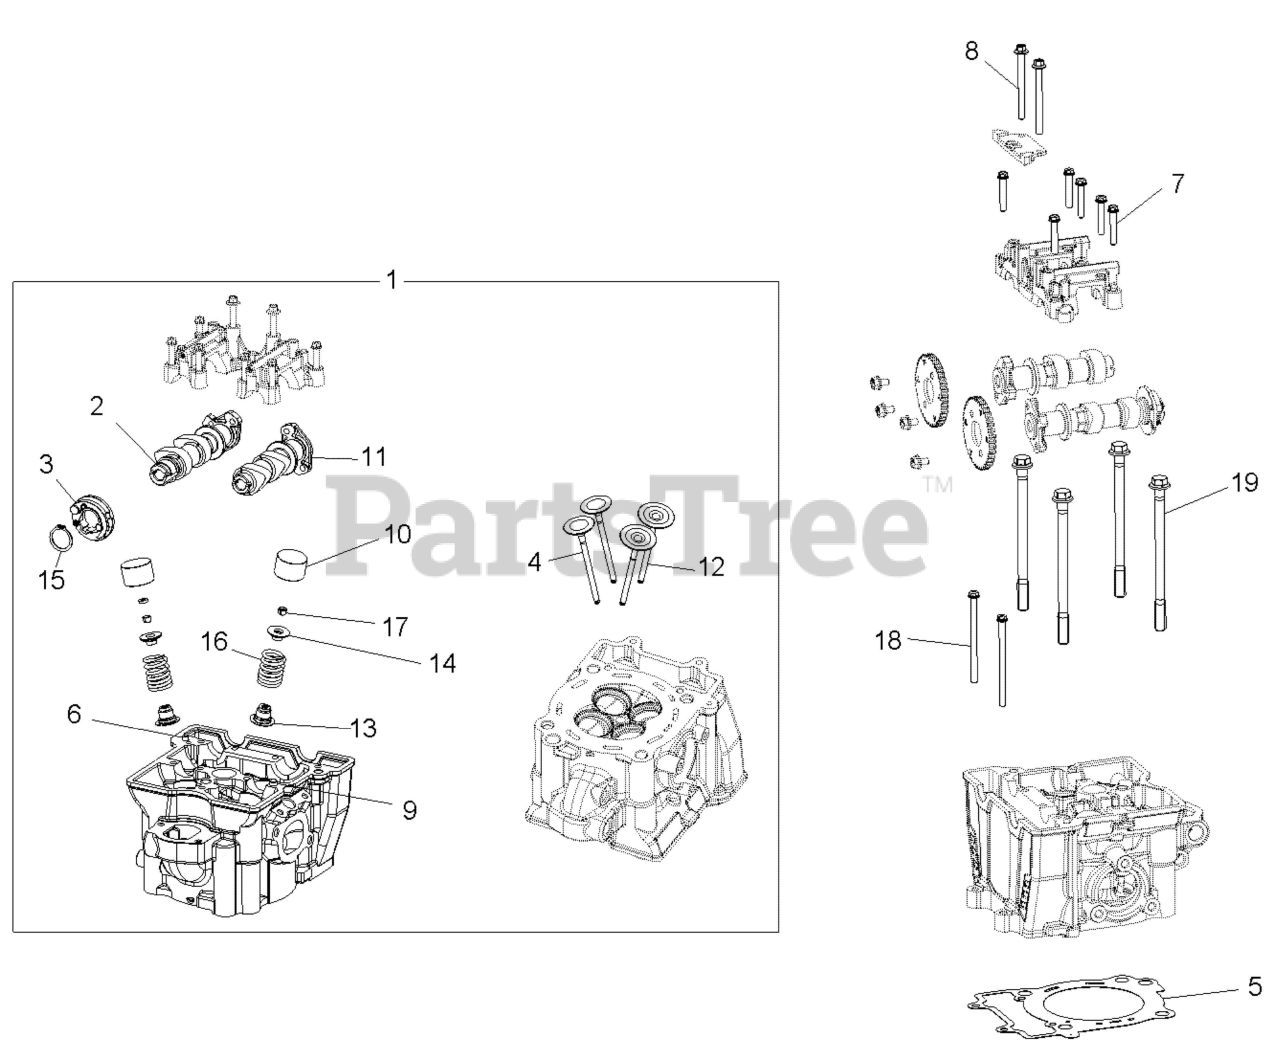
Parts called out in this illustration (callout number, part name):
1	ASM, CYLINDER HEAD, 1CYL, MACH
2	CAMSHAFT-EXH,MACH
3	ASM-DECOMP SYSTEM,LH
4	VALVE-INTAKE,STEEL
5	GASKET-CYL HEAD
6	PIN, DOWEL
7	SCR, HXFL M6X1.0X35 10.9
8	SCR, HXFL M6X1.0X70 10.9
9	DOWEL-HOLLOW M8X8
10	TAPPET-VALVE,GRADED 4.400
10	TAPPET-VALVE,GRADED 4.425
10	TAPPET-VALVE,GRADED 4.450
10	TAPPET-VALVE,GRADED 4.475
10	TAPPET-VALVE,GRADED 4.500
10	TAPPET-VALVE,GRADED 4.525
10	TAPPET-VALVE,GRADED 4.550
10	TAPPET-VALVE,GRADED 4.575
10	TAPPET-VALVE,GRADED 4.600
10	TAPPET-VALVE,GRADED 4.625
10	TAPPET-VALVE,GRADED 4.650
10	TAPPET-VALVE,GRADED 4.675
10	TAPPET-VALVE,GRADED 4.70
10	TAPPET-VALVE,GRADED 4.725
10	TAPPET-VALVE,GRADED 4.750
10	TAPPET-VALVE,GRADED 4.775
10	TAPPET-VALVE,GRADED 4.800
10	TAPPET-VALVE,GRADED 4.825
10	TAPPET-VALVE,GRADED 4.850
10	TAPPET-VALVE,GRADED 4.875
10	TAPPET-VALVE,GRADED 4.900
10	TAPPET-VALVE,GRADED 4.925
10	TAPPET-VALVE,GRADED 4.950
10	TAPPET-VALVE,GRADED 4.975
10	TAPPET-VALVE,GRADED 5.000
10	TAPPET-VALVE,GRADED 5.025
10	TAPPET-VALVE,GRADED 5.050
10	TAPPET-VALVE,GRADED 5.075
10	TAPPET-VALVE,GRADED 5.100
10	TAPPET-VALVE,GRADED 5.125
10	TAPPET-VALVE,GRADED 5.150
10	TAPPET-VALVE,GRADED 5.175
10	TAPPET-VALVE,GRADED 5.200
10	TAPPET-VALVE,GRADED 5.225
10	TAPPET-VALVE,GRADED 5.250
10	TAPPET-VALVE,GRADED 5.275
10	TAPPET-VALVE,GRADED 5.300
10	TAPPET-VALVE,GRADED 5.325
10	TAPPET-VALVE,GRADED 5.350
10	TAPPET-VALVE,GRADED 5.375
10	TAPPET-VALVE,GRADED 5.400
10	TAPPET-VALVE,GRADED 5.425
10	TAPPET-VALVE,GRADED 5.450
11	CAMSHAFT-INTAKE,MACH
12	VALVE-EXHAUST,INCONEL
13	SEAT-W/SEAL,VALVE SPRING
14	RETAINER,VALVE
15	RING-SNAP EXT 23MM
16	SPRING, VALVE
17	KEEPER-VALVE
19	BOLT, HEAD,M11X1.0X1.25X150
